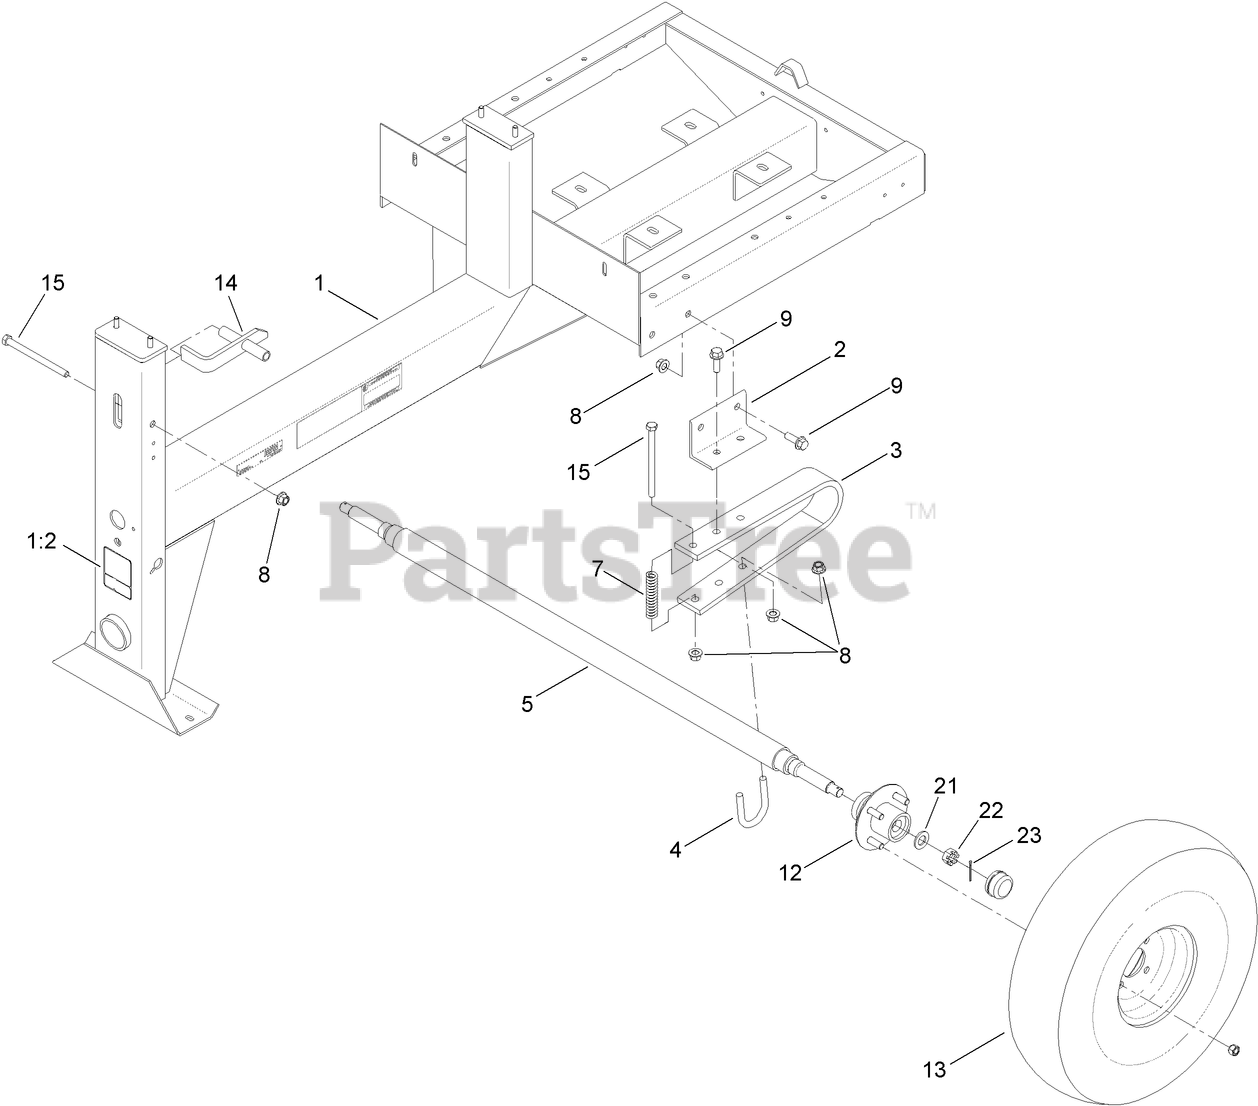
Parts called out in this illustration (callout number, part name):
1	FRAME ASM
1:2	DECAL-SAFETY CHAIN, TOWING
2	BRACKET-AXLE, SPRING
3	SPRING-LEAF
4	BOLT-U
5	AXLE-SPRING
7	SPRING-COIL
8	NUT-LOCK
9	SCREW-HHF
12	HUB ASM
13	TIRE AND RIM ASM
14	LATCH-DRUM
15	SCREW-HH
21	WASHER-FLAT
23	PIN-COTTER
